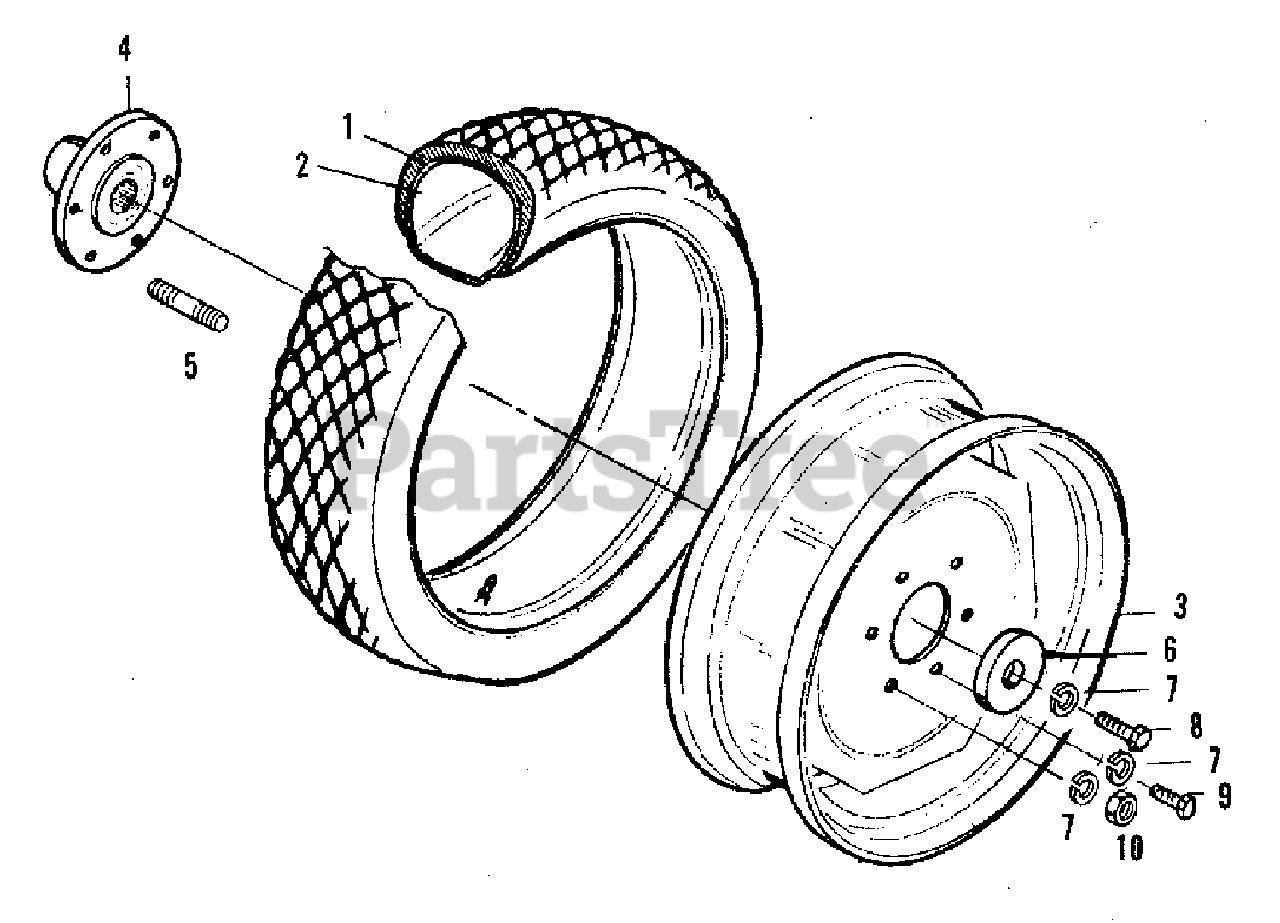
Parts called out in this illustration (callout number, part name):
1	TIRE TURF (Obtain Locally)
2	TUBE (Obtain Locally)
4	HUB, rear turf
6	PLATE, hub
7	LOCKWASHER
